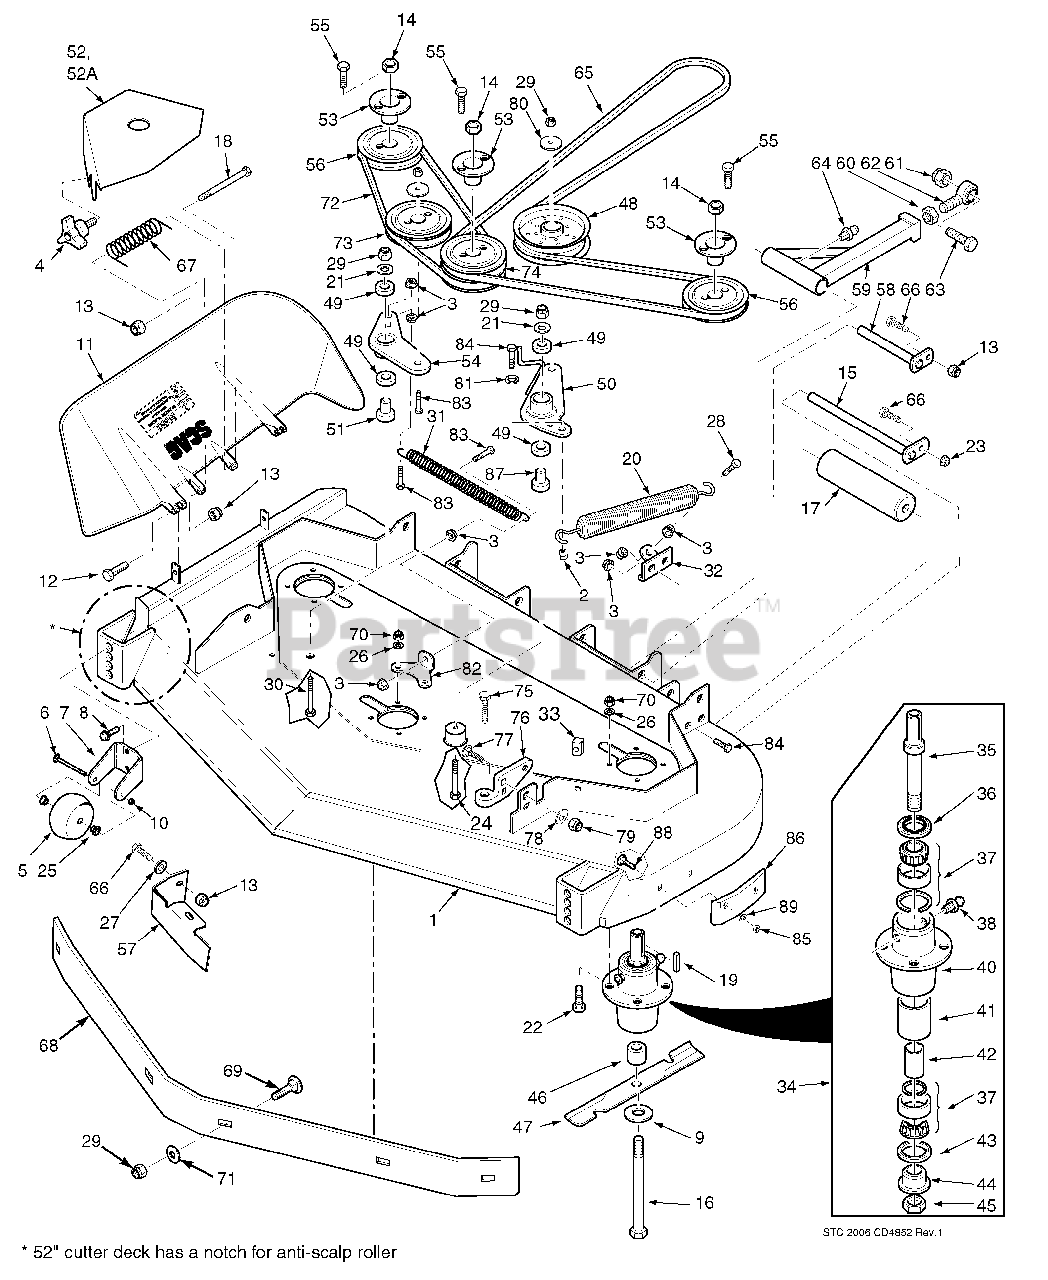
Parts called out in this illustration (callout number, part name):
1	Cutter Deck Velocity Plus
2	Boss, Spring Anchor
3	Nut, 3/8-16 Serrated Flange
4	Wing Nut, 3/8-16
5	Anti-Scalp Wheel
6	Bolt, Carriage 3/8-16 x 4"
7	Bracket, Anti-Scalp Wheel
8	Bolt, Serrated Flange 3/8-16 x 1"
9	Flatwasher, 5/8" Hardened
10	Locknut, 3/8-16 Center Lock
11	Discharge Chute
12	Bolt, Hex Head 5/16-18 x 1-1/2", Rear
13	Nut, Elastic Stop 5/16-18
14	Nut, 5/8-11 UNC
15	Shaft, Roller
16	Bolt, Hex Head 5/8-11 x 9-1/2"
17	Roller, Rear
18	Bolt, Hex Head 5/16-18 x 4-3/4"
19	Key, 1/4 x 1/4 x 2"
20	Spring, Idler LH
21	Flatwasher, 3/8"
22	Bolt, Hex Head 5/16-18 x 1-3/4" Grade 8
23	Nut, Serrated Flange 5/16-18
24	Bolt, Hex Head 3/8-16 x 3-3/4"
25	Bushing, .376 ID Oilite
26	Lockwasher 5/16"
27	Flatwasher 5/16"
28	Bolt, Hex Head 3/8-16 x 1-1/2" Gr. 8
29	Nut, Elastic Stop 3/8-16
30	Bolt, Hex Head 3/8-16 x 2-1/2"
31	Spring, Idler RH
32	Bracket, Spring Anchor LH
33	U-Nut, 3/8-16
34	Spindle Assembly
35	Shaft, Spindle
36	Seal Upper
37	Bearing Assembly
38	Grease Fitting
39	Valve, Grease Relief
40	Housing, Spindle
41	Spacer, Outside
42	Spacer, Inside
43	Seal, Lower
44	Bushing, Bottom
45	Nut, Special 1-1/16 - 18
46	Spacer, Spindle
47	Cutter Blade 16.5"
47	Cutter Blade 18"
48	Pulley, Idler 5" Dia.
49	Bearing
50	Idler Arm Assy.
51	Idler Pivot
52	Belt Cover
52A	Belt Cover
53	Hub, Tapered 1-1/8" Bore
54	Idler Arm
55	Bolt, Hex Head 1/4-20 x 1" Grade 8
56	Pulley 4.75"
56	Pulley 5.35"
57	Turbo Baffle, Bolt On
58	Push Arm Shaft
59	Push Arm
60	Nut, 5/8-18 UNF
61	Nut, Elastic Stop 5/8-11
62	Rod End, 5/8 Male RH Thread
63	Bolt, Hex Head 5/8-11 x 4-1/2"
64	Grease Fitting, 90 Degree
65	Belt, Cutter Deck Drive
66	Bolt, Hex Head 5/16-18 x 1"
67	Spring, Discharge Chute
68	Baffle Weldment
69	Bolt, Carriage 3/8-16 x 1"
70	Nut, Elastic Stop 5/16-18 Grade 8
71	Flatwasher 3/8"
72	Belt, RH Cutter Deck
73	Pulley, Idler 5" Dia.
74	Pulley, Double Groove
75	Bolt, Special
76	Lever Assy., Deck Level
77	Bolt, Carriage 7/16-14 x 1-1/4"
78	Flatwasher, 7/16-.500 x 1.25 x .083
79	Nut, Elastic Stop 7/16-14
80	Dust Shield
81	Lockwasher 3/8"
82	Bracket, Spring Anchor RH
83	Bolt, Hex Head 3/8-16 x 1-1/2" Gr. 8
84	Bolt, Hex Head 3/8-16 x 1"
85	Bolt, Hex Head 3/8-16 x 1"
86	Bolt, Hex Head 3/8-16 x 1-1/2" Gr. 8
87	Idler Pivot
88	Bolt, Carraige 5/16-18 x 3/4"
89	Flatwasher, 5/16"
90	Nut, Center Lock 5/16-18
91	Wear Pad
